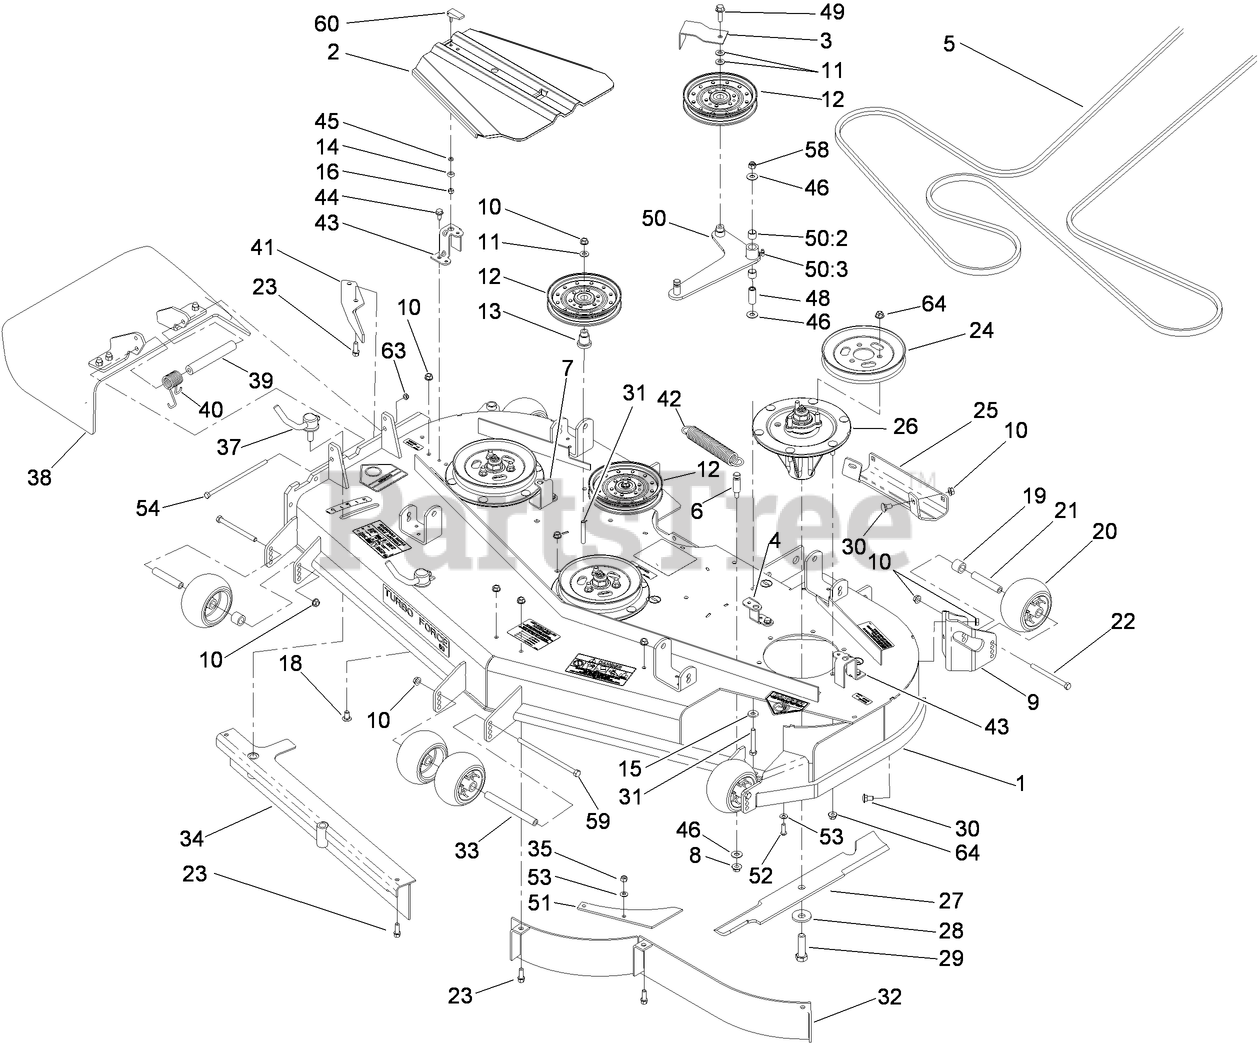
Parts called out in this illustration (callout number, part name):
1	DECK DECAL ASM
2	COVER-BELT
3	GUIDE-BELT
4	BRACKET-COVER, TALL
5	BELT-V
6	PIN-THREADED, SPRING ANCHOR
7	BRACKET-COVER
8	NUT-HF
9	MOUNT-WHEEL, LH
10	NUT-HHF, WHIZ
11	WASHER-FLAT
12	Idler-Flat
13	MOUNT-PULLEY
14	BUSHING-LATCH, SWELL
15	WASHER-BELLEVILLE
16	NUT-LOCK, HH
18	SCREW-CARR
19	TUBE-SPACER
20	ROLLER-SCALP, ANTI
21	TUBE-SPANNER
22	SCREW-HH
23	SCREW-HWH
24	Pulley
25	Plate-Skid
26	SPINDLE ASM
27	BLADE-HI FLOW
28	Washer-Blade Bolt, Heavy
29	SCREW-BLADE
30	SCREW-CARR
31	SCREW-HH
33	SPACER-WHEEL
35	NUT-LOCK, NI
37	LEVER ASM
38	RUBBER DEFLECTOR ASM
39	SPACER
40	SPRING-TORSION
41	BAFFLE-DISCHARGE
42	SPRING-EXTENSION
43	BRACKET-COVER
44	SCREW-HWHTF
45	WASHER
46	WASHER-FLAT
48	BUSHING
49	SCREW-HHF
50	DECK IDLER ARM ASM
50:2	SLEEVE-BEARING
50:3	FITTING-GREASE, 90 DEG
51	PLATE-TURBO
52	SCREW-HSBH
53	WASHER-SPRING
54	SCREW-HH
58	NUT-LOCK, NI
59	SCREW-HH
60	HANDLE-LATCH, SWELL
63	NUT-LOCK, NI
64	NUT-HF, NI
